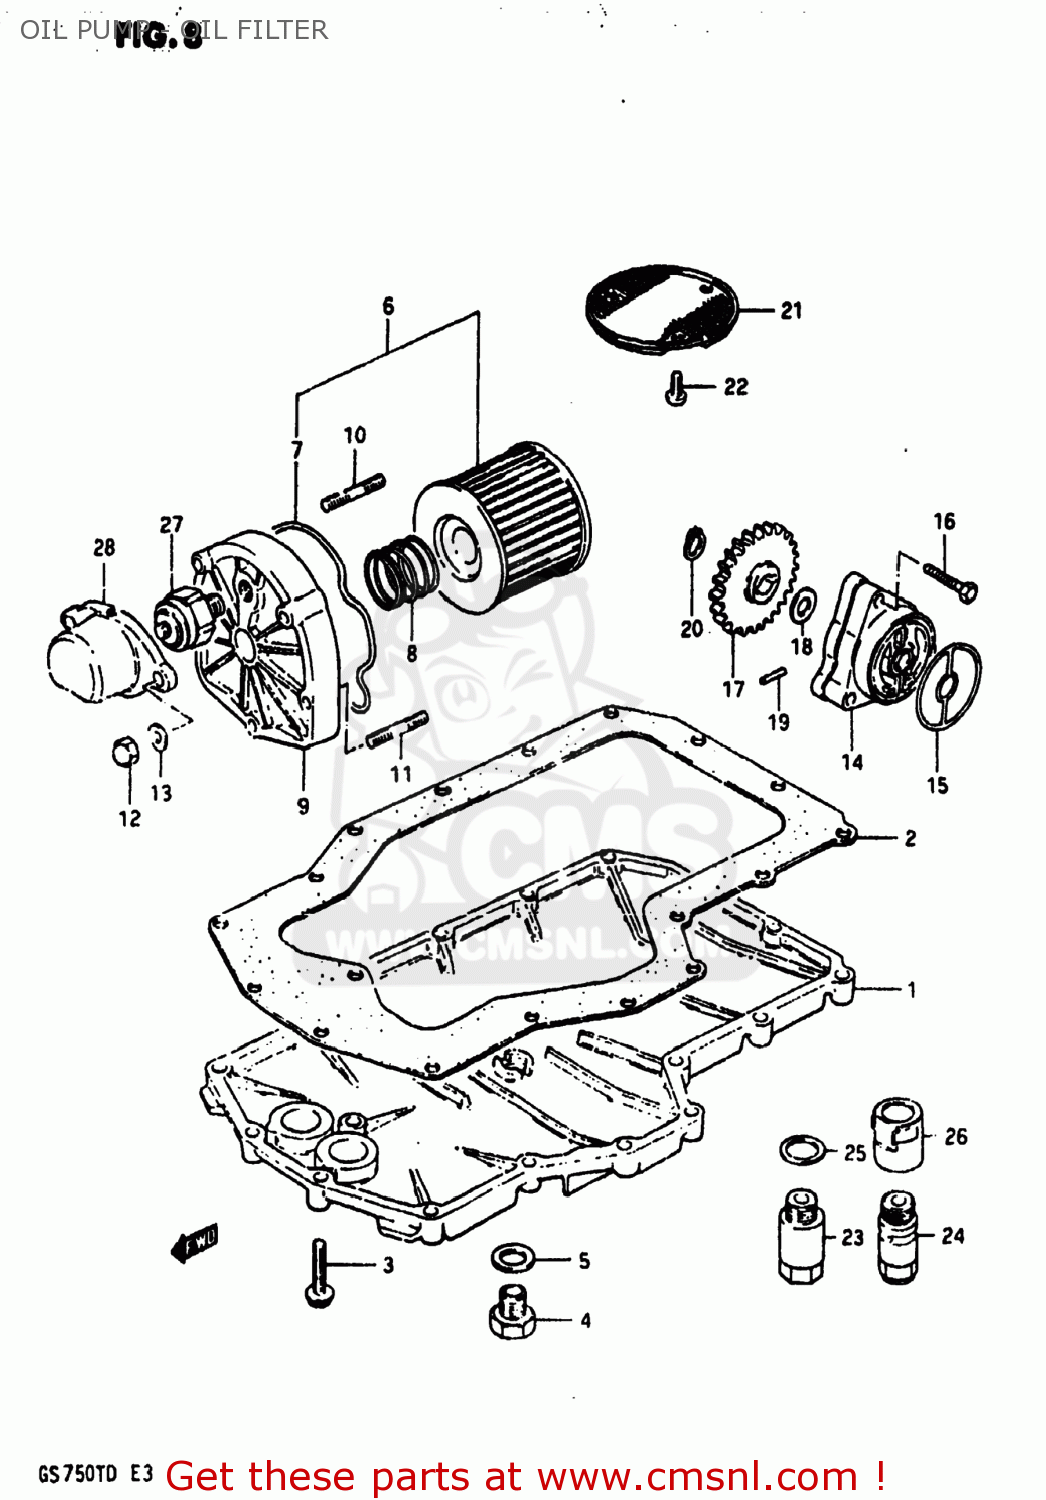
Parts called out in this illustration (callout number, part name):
1	PAN,OIL
2	GASKET,OIL PAN (MCA)
3	BOLT
4	PLUG
5	GASKET(14X19.2X2) (NAS)
6	FILTER ASSY,ENGINE OIL
7	O RING,OIL FILTER CHAMBER CAP
8	SPRING
9	CAP,ENGINE OIL FILTER
10	STUD 6X30
11	STUD 6X25
12	NUT
13	WASHER
14	PUMP ASSY,ENGINE OIL
15	O-RING,OIL PUMP
16	BOLT(6X32)
17	GEAR,ENG OIL PUMP DRIVEN
18	SHIM
19	PIN(4X15.8)
20	CIRCLIP
21	STRAINER,ENGINE OIL
22	SCREW 6X12
23	VALVE ASSEMBLY,OIL RELIEF
24	VALVE ASSEMBLY,OIL RELIEF
25	WASHER
26	GUIDE, OIL REGULATOR
27	SWITCH ASSEMBLY
28	COVER,OIL PRESSURE SWITCH
